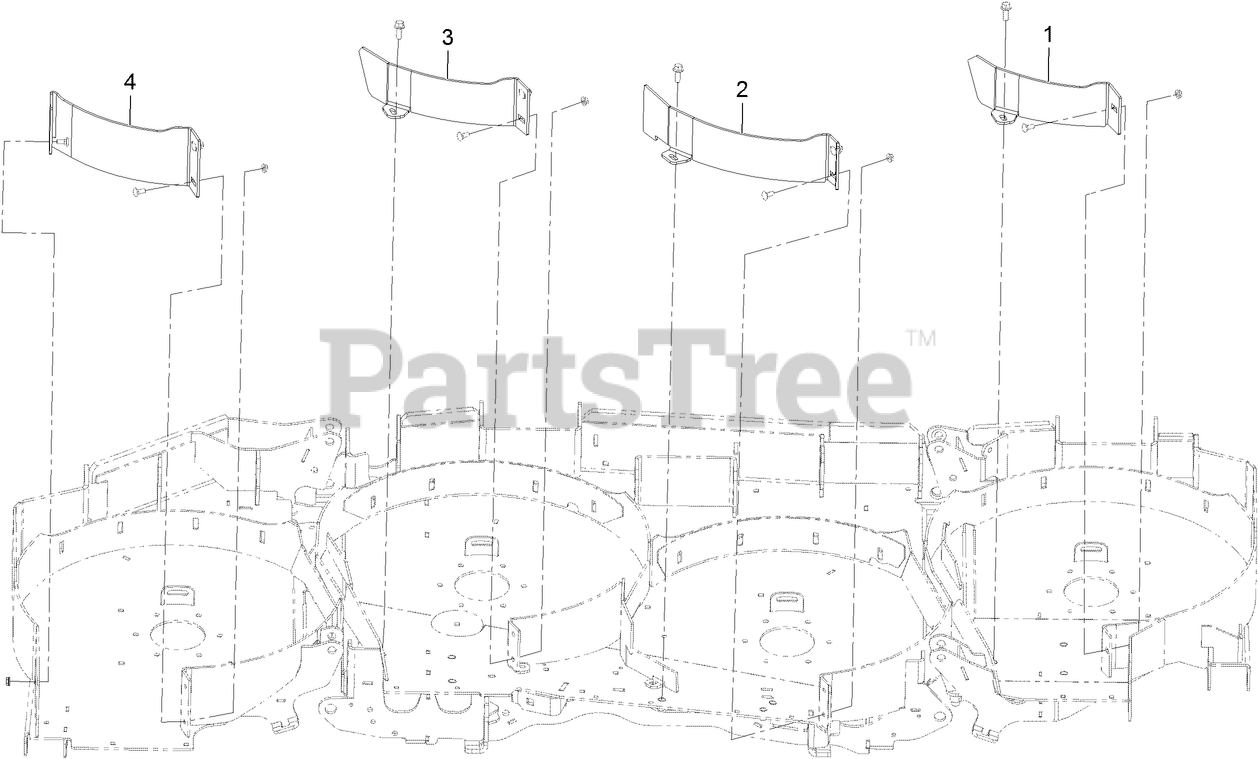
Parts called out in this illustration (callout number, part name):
1	BAFFLE-BLOCK, LH WING
2	BAFFLE-BLOCK, LH CTR
3	BAFFLE-BLOCK, RH CTR
4	BAFFLE-BLOCK, RH WING
